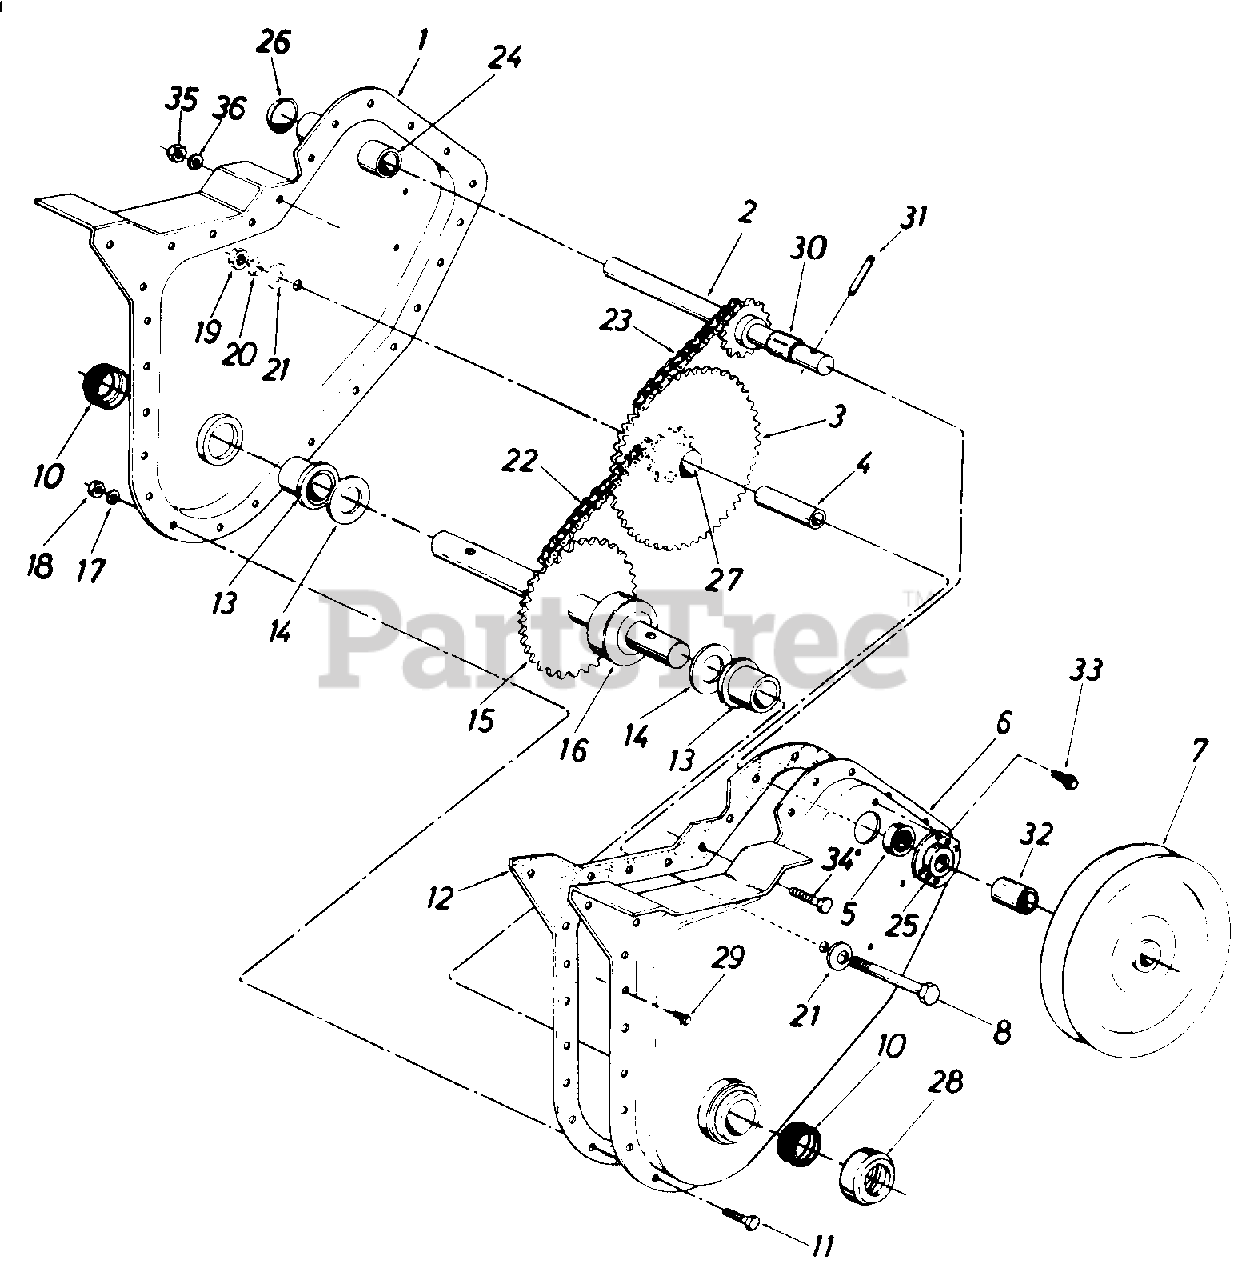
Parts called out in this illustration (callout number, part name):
1	Chain Case Ass'y.--R.H.
2	Input Shaft Ass'y.
3	Hub and Sprocket Ass'y.
4	Bearing Inner Race
5	Ball Bearing
6	Chain Case Ass'y.--L.H.
7	Pulley--Chain Case
8	Hex Bolt 3/8-24 x 2.5" Lg.
10	Seal
11	Hex Bolt 1/4-28 x .625" Lg.
12	Gasket
13	Flange Brg. .879" I.D.
14	Fl-Wash. .88" I.D. x 1.5"
15	Tine Shaft Ass'y.
16	Spacer 7/8" I.D. x 2" O.D. x .68" Lg.
17	L-Wash. 1/4" I.D.
18	Hex Nut 1/4-28 Thd.
19	Hex Ins. L-Nut 3/8-24 Thd.
20	L-Wash. 3/8" I.D.
21	Bell-Wash. .406" I.D.
22	Chain #420 1/2" Pitch x 37 Links
23	Chain #35 .375" Pitch x 49 Links
24	Bearing .62" I.D. x .813"
25	Bearing Housing
26	Expansion Plug 13/16" Dia.
28	Dust Cap
29	Hex Wash. Hd. Self-Tap Scr. 1/4-20 x .50" Lg.
30	Spacer .63" I.D. x .77" O.D. x .38" Lg.
31	Spring Pin Spiral 1/4" Dia. x 1 1/2" Lg.
32	Spacer .647 x 1.25"
33	Hex Wash. Hd. Self-Tap Scr. 1/4-20 x .38" Lg.
34	Hex Bolt 5/16-18 x .75" Lg.
35	Hex Nut 5/16-18 Thd.
36	L-Wash. 5/16" I.D.
